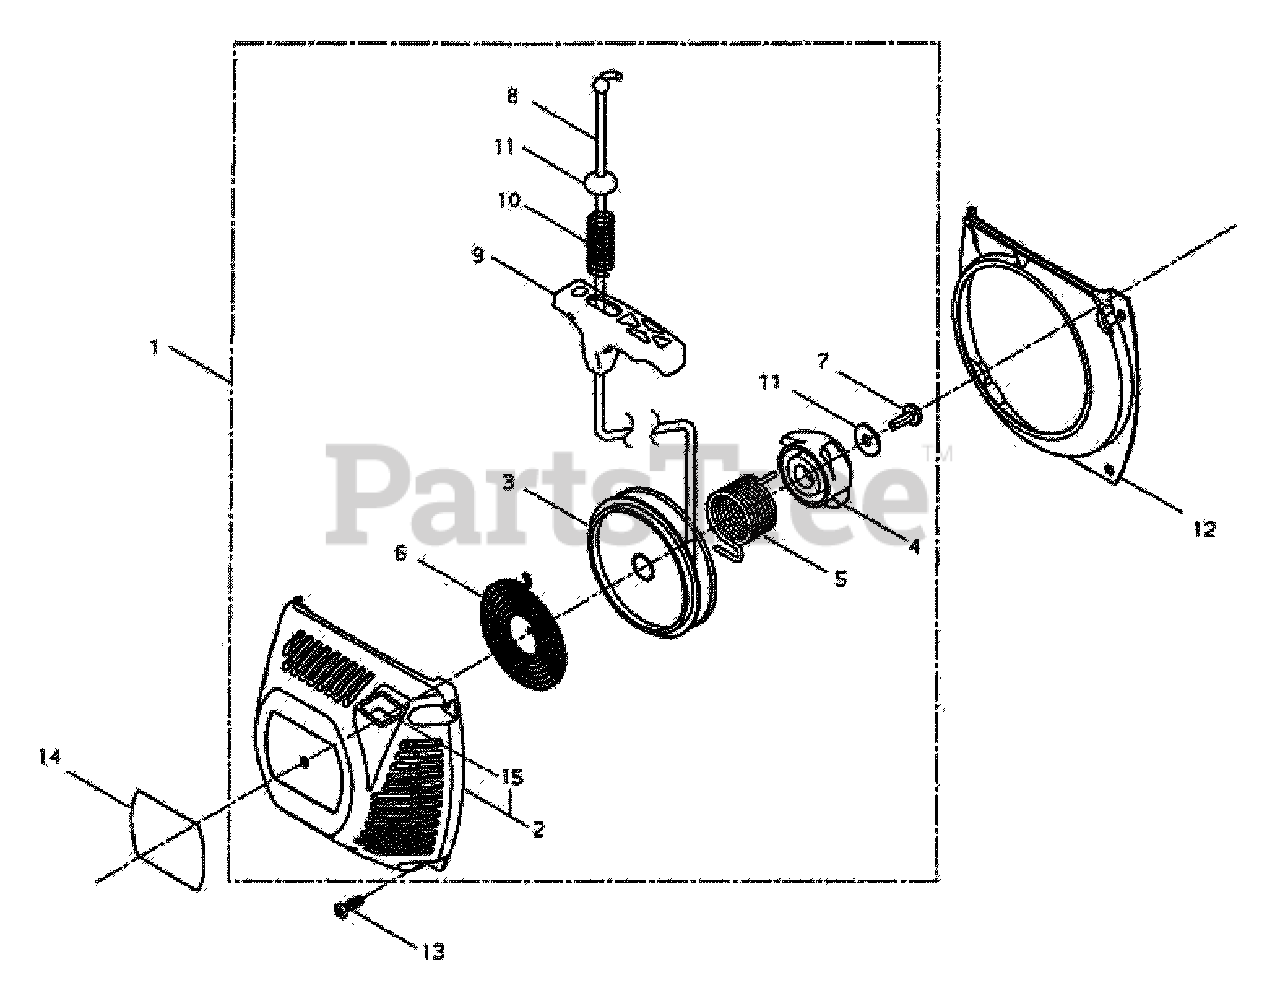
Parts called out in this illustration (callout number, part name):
1	STARTER ASSY
2	CASE, STARTER
3	REEL, ROPE
4	PAWL CATCHER
5	SPRING
6	SPRING, RECOIL
7	SCREW 5
8	ROPE, STARTER Ø3.8×750
9	KNOB
10	SPRING, COMPRESSION
11	RETAINER, ROPE
12	DEFLECTOR, AIR
13	BOLT, ADHESIVE
14	LABEL - MODEL
15	GUIDE, ROPE
